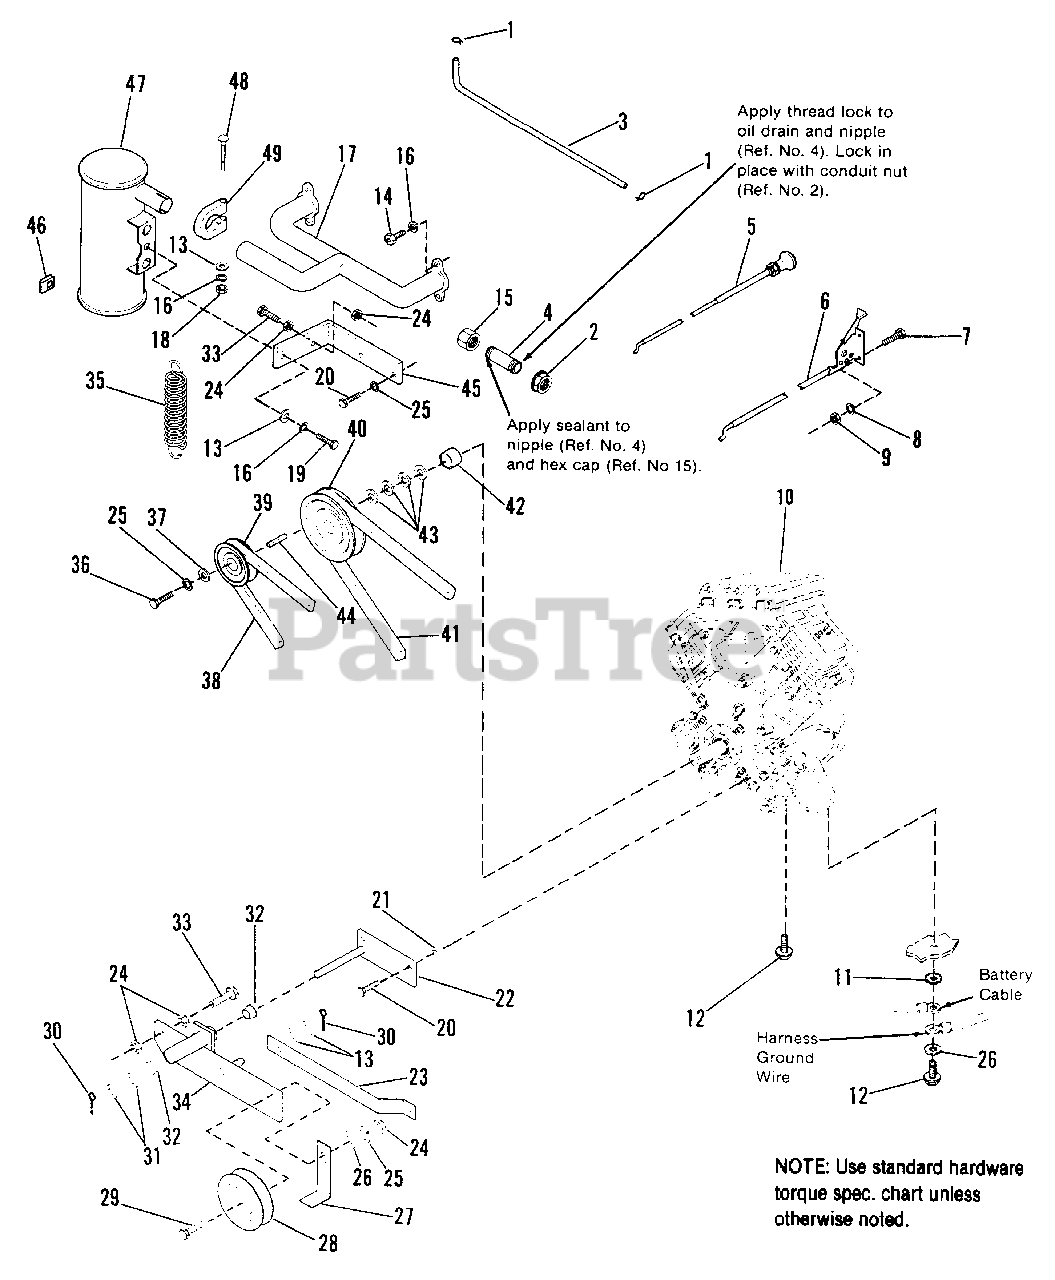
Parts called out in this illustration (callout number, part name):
1	CLAMP, Hose
2	NUT, Conduit, 3/8-18
3	HOSE, Fuel (Cut to 24" length)
4	NIPPLE, Pipe, 3/8-18 x 1
5	CHOKE CABLE
6	THROTTLE CABLE
7	SCREW, Pan Head Phillips, #10-24 x 1
8	LOCKWASHER, Spring, #10
9	NUT, Hex, #10-24
10	ENGINE, 16 HP Briggs & Stratton
11	LOCKWASHER, Ext. Tooth, 3/8
12	SCREW, Taptite, 3/8-16 x 1-1/2
13	WASHER, Plain
14	CAPSCREW, Hex Socket Hd., 8 x 1-1/4 x 20 mm
15	CAP, Hex, 3/8-18 NPT
16	LOCKWASHER, Spring, 5/16
17	MANIFOLD ASSY., Exhaust
18	NUT, Hex, 5/16-18
19	CAPSCREW, Hex, 5/16-18 x 3/4
20	CAPSCREW, Hex, 3/8-16 x 1
22	IDLER PIVOT ASSY.
23	LINK, Clutch
24	NUT, Hex, 3/8-16
25	LOCKWASHER, Spring, 3/8
26	WASHER, Plain
27	RETAINER, Belt
28	V-PULLEY, Idler, PTO
29	CAPSCREW, Hex, 3/8-16 x 1-1/2
31	WASHER, Plain
32	BEARING, Flanged
33	CAPSCREW, Hex, 3/8-16 x 1-3/4
34	IDLER ARM ASSY.
36	CAPSCREW, Hex, 3/8-24 x 1-1/2
37	WASHER, Plain
38	V-BELT, Traction
39	V-PULLEY, Traction
40	V-PULLEY, PTO
41	V-BELT, PTO
42	SPACER, Engine
43	WASHER, Plain
44	KEY, Square, 1/4 x 1-3/4
45	SUPPORT, Muffler
46	PAL NUT, 5/16-18
47	MUFFLER ASSY.
48	CARRIAGE BOLT, 5/16-18 x 2-3/4
49	CLAMP, Muffler
